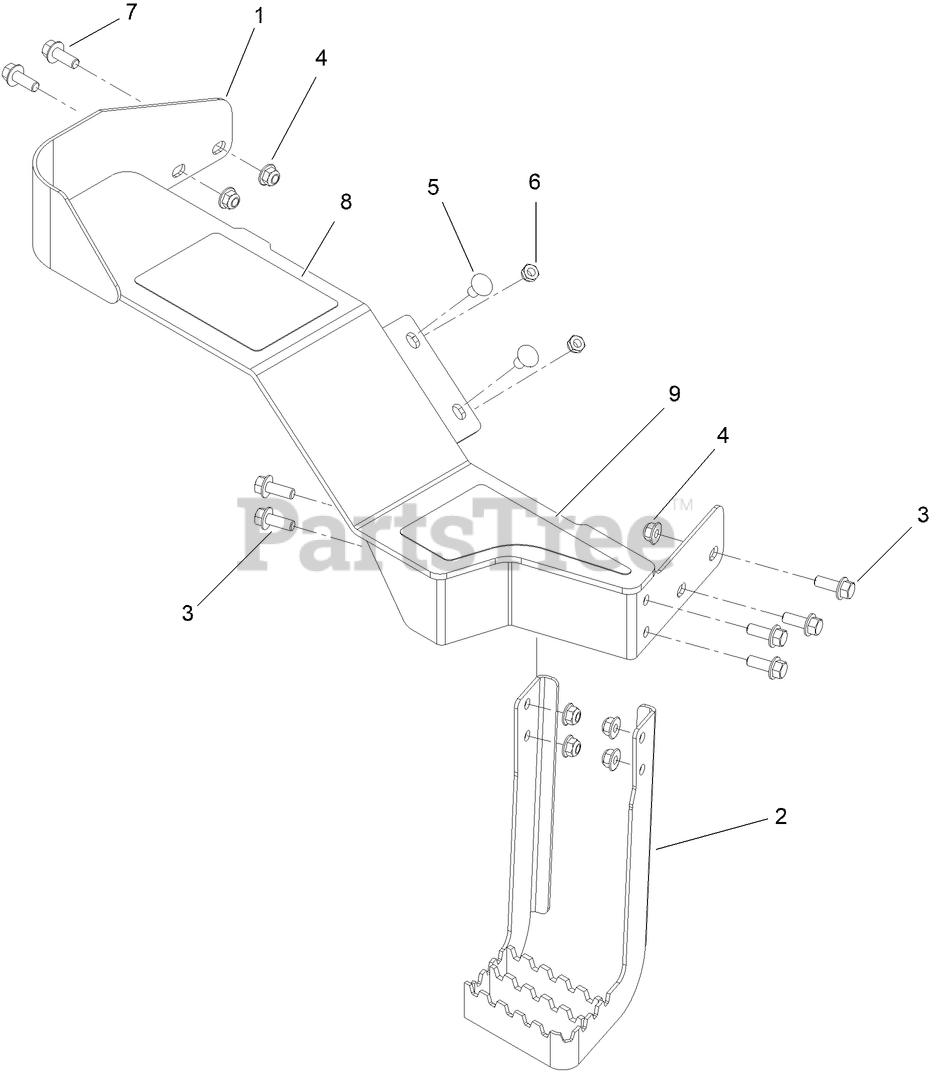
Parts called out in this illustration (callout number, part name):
1	PLATFORM-EXTENSION
2	STEP-PLATFORM
3	SCREW-HHF
4	NUT-HF, NI
5	SCREW-CARR
6	NUT-HEX
7	SCREW-HHF
8	NON-SKID
9	NON-SKID
